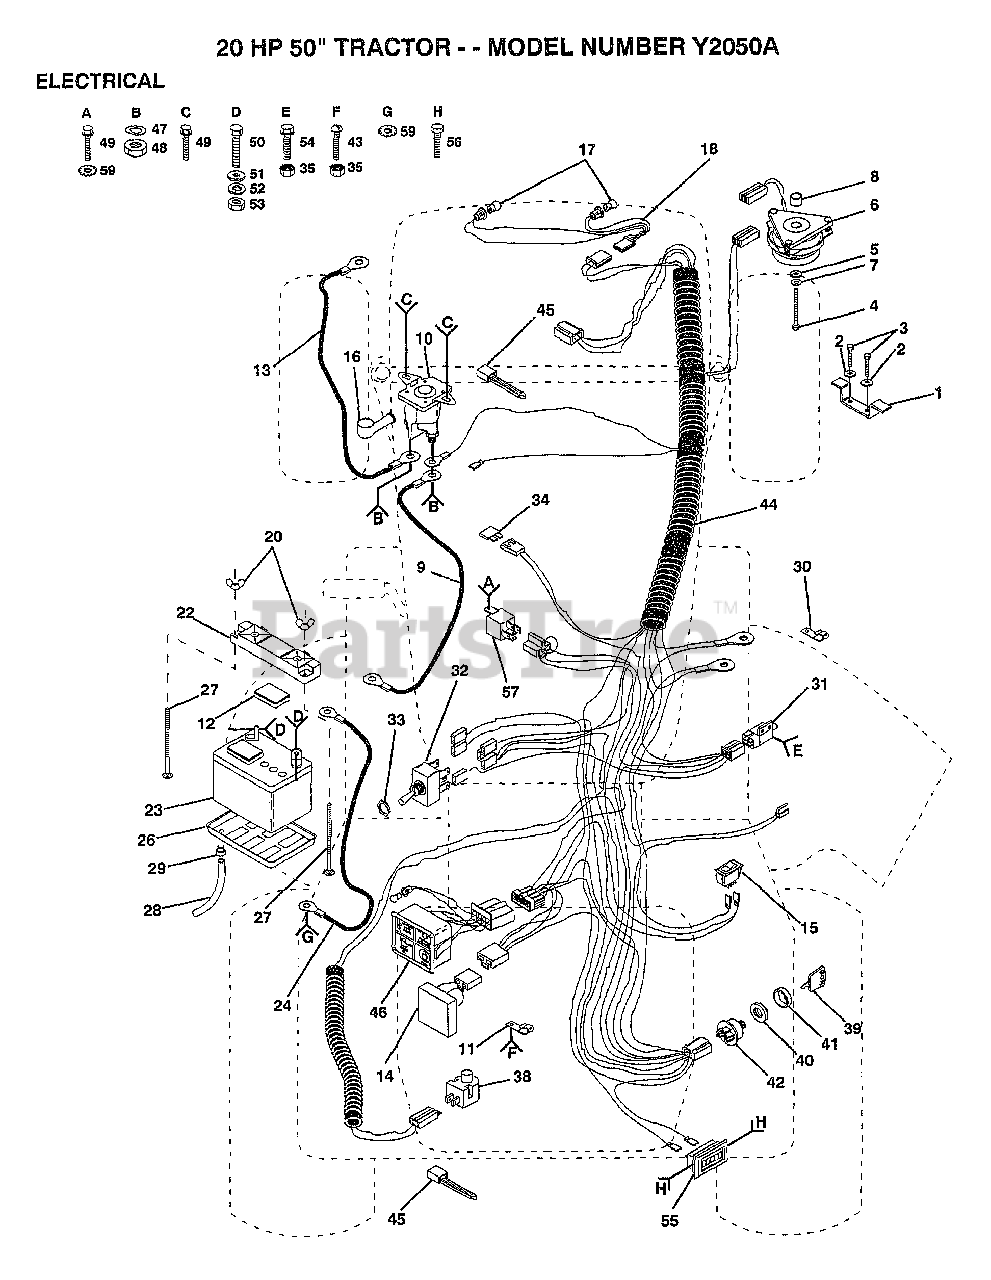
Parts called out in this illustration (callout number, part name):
2	LOCKWASHER
3	BOLT
5	WASHER
7	LOCKWASHER
8	SPACER-CLUTCH
9	CABLE-BATTERY T
12	"CAP,BATTERY "
13	"CABLE,STARTER T"
14	SENSOR LOW VOLT T
15	SWITCH LT
24	CABLE T
26	"TRAY T, BATTERY"
27	BOLT
29	HOSE CLAMP T
30	CLIP GTV
31	SWITCH INTERLOCKT
33	HEX NUT T
34	FUSE HYT
35	"NUT,KEPS"
38	SWITCH SEAT
39	KEY
40	NUT IGNITION
44	HARNESS
45	WIRE TIE
46	INDICATORLIGHTT
48	NUT
49	SCREW ST
50	BOLT LT
51	WASHER
52	LOCKWASHER
54	SCREW
55	HOUR METER T
56	SCREW
57	RELAY ASSY T
59	LOCKWASHER
